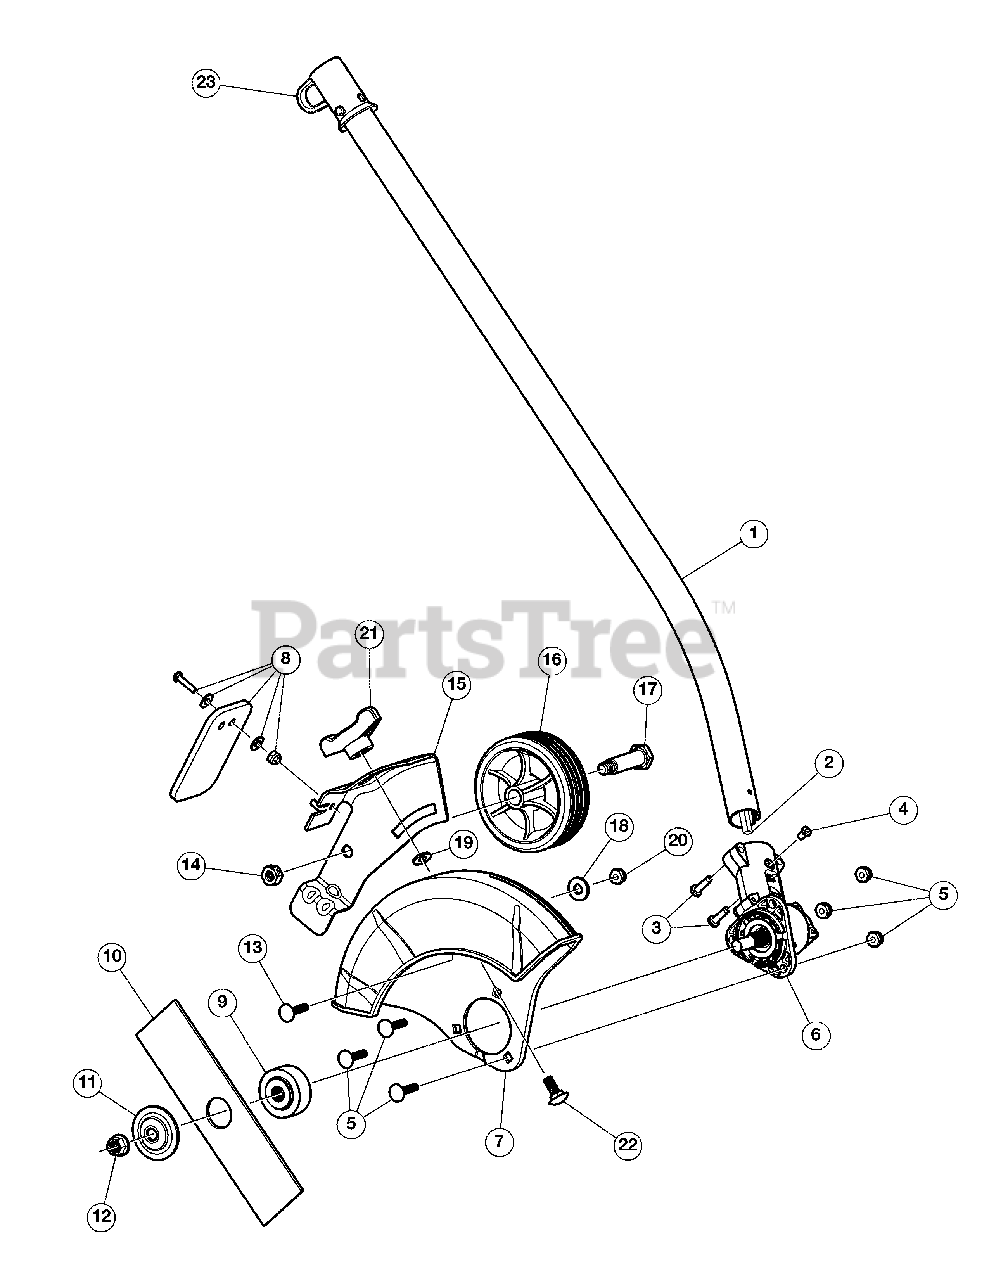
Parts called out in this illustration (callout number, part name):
1	Boom Assembly
2	Drive Shaft
3	Boom Mounting Hardware
4	Anti-Rotation Screw
5	Guard Mounting Hardware
6	Gearbox Assembly
7	Blade Guard
8	Deflector w/Hardware
9	Spacer
10	Blade
11	Blade Clamp Washer
12	Blade Retainer Nut
13	Wheel Bracket Mounting Bolt
14	Nut
15	Edger Guide
17	Shoulder Bolt
21	Edger Guide Knob
